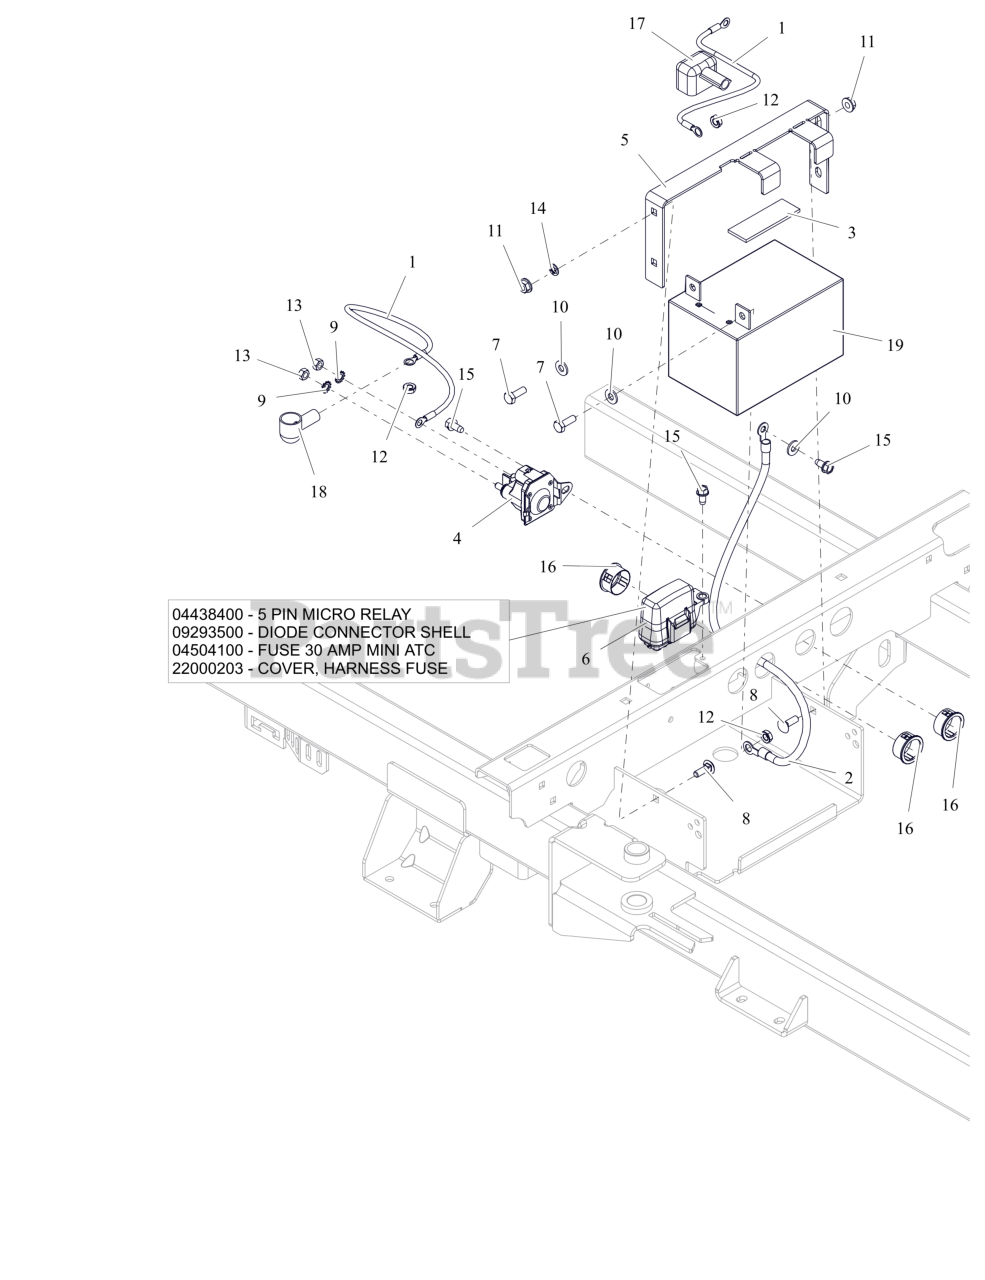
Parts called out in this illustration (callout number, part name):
1	CABLE,POS W/2 1/4 RING 15.0 LG
2	CABLE-NEGATIVE BATTERY 24.00"
3	PAD,RBR 1.0"X3.0" W/ADHESIVE
4	SOLENOID, STARTER (SEALED)
5	BRKT, BATTERY HOLD-DOWN (BLACK)
6	HARNESS, WIRE
6	RELAY,MICRO5 TERML W/RESISTOR
6	DIODE, CONNECTOR SHELL
6	FUSE,30 AMP MINI-ATC
6	COVER, FUSE
7	BLT, HEX .25-20X.75 G5 ZCC
8	BLT, RHSN .25-20X.750 G5 ZCC
9	WSHR,LK-EXT.262X.502X.026 ZCC
10	WSHR,FLT .281X.625X.065 ZCC
11	NUT-LK-TOP-FLG .250-20 GF ZCC
12	NUT-KEPS .250-20 ZCC
13	NUT-STD M6-1.0 ZCC
14	NUT-PUSH .25X.50 O.D.
15	SCR-TAP .25-20X.50 HWH ZCC
16	BSHG, PANEL SNAP .937X1.11X.56
17	INSULATOR
18	BOOT, EYELET TERMINAL
19	BATTERY, 12V 12A -190CCA
